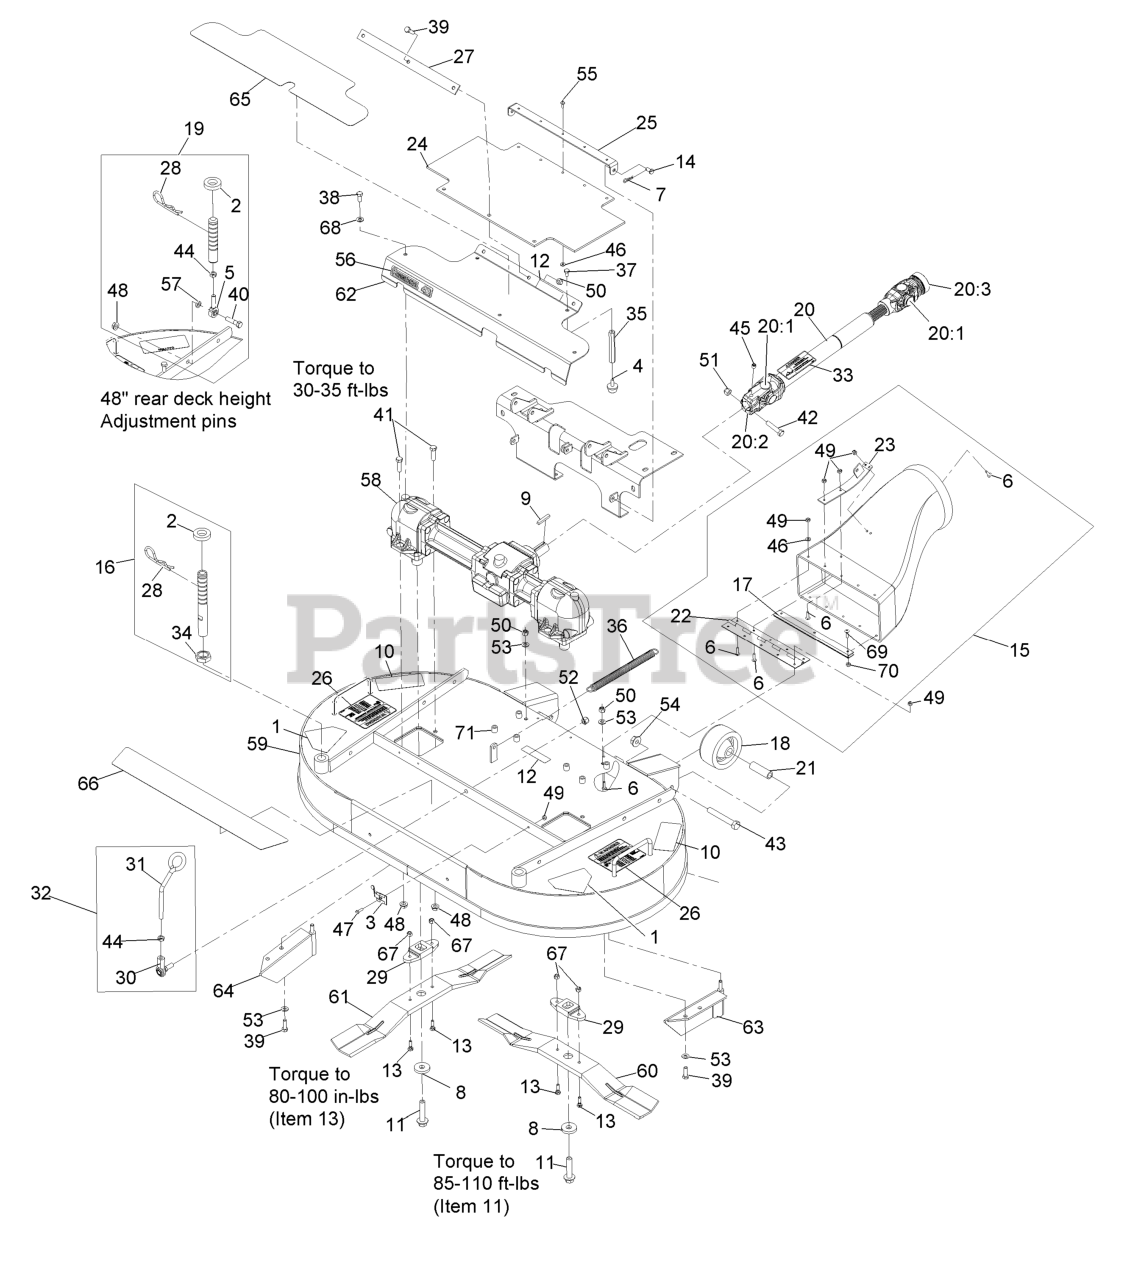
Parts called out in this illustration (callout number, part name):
1	DECAL-DANGER
2	SPACER-DECK SUPPORT
3	CLIP-DECK, HOLD UP ROD
4	BUMPER-RUBBER
5	BALLJOINT
6	SCREW-HEAD, TRUSS
7	PIN-COTTER
9	KEY-SQUARE
10	DECAL-TORQUE
11	BOLT-BLADE
12	DECAL-COVER, MISSING
13	BOLT-SHEAR
14	PIN-CLEVIS
15	DISCHARGE TUBE ASM
16	FRONT DECK HEIGHT ADJUST
17	GUARD-PLENUM
18	ROLLER-DECK
19	REAR DECK HEIGHT ADJUST A
20	DRIVE SHAFT ASM
20:2	YOKE-KEYED
20:3	YOKE-QUICK DISCONNECT
21	SPACER-ROLLER
22	HINGE-PIANO
23	MOUNT-SPRING
24	GUARD-PTO
25	BRACKET-GUARD, PTO
27	STRAP-DRIVE, LINE COVER
28	PIN-CUT HEIGHT
29	DRIVER-BLADE
30	BALLJOINT-RH
31	LATCH-DECK
32	DECK LATCH ASM
33	DECAL-DRIVELINE
34	NUT-JAM
35	STAND-OFF
36	SPRING-EXTENSION
37	SCREW-HH
38	SCREW-HH
39	SCREW-HH
40	SCREW-HH
41	SCREW-HH
42	SCREW-HH
43	SCREW-HH
44	NUT-HEX
45	SCREW-SET, HSH
46	WASHER-FLAT
48	NUT-HHF, WHIZ
49	NUT-LOCK, NI
50	NUT-LOCK, NI
51	NUT-LOCK, NI
52	NUT-LOCK
53	WASHER-SPRING
54	NUT-HHF
55	RIVET-BLIND
56	DECAL,COMMERCIAL 48
57	SPACER-IDLER
58	GEAR BOX ASM
59	DECK DECAL AND BAFFLE ASM
60	BLADE,25 INCH LH
61	BLADE,25 INCH RH
62	ASM,GEARBOX COVER 48 W/DE
63	BAFFLE-LH
64	BAFFLE-RH
65	PAD-ANTI SKID
66	PAD-ANTI SKID
67	NUT-LOCK, NI
68	WASHER-PLAIN
69	BOLT-CARR
70	NUT-LOCK, NI
71	NUT-CLINCH
